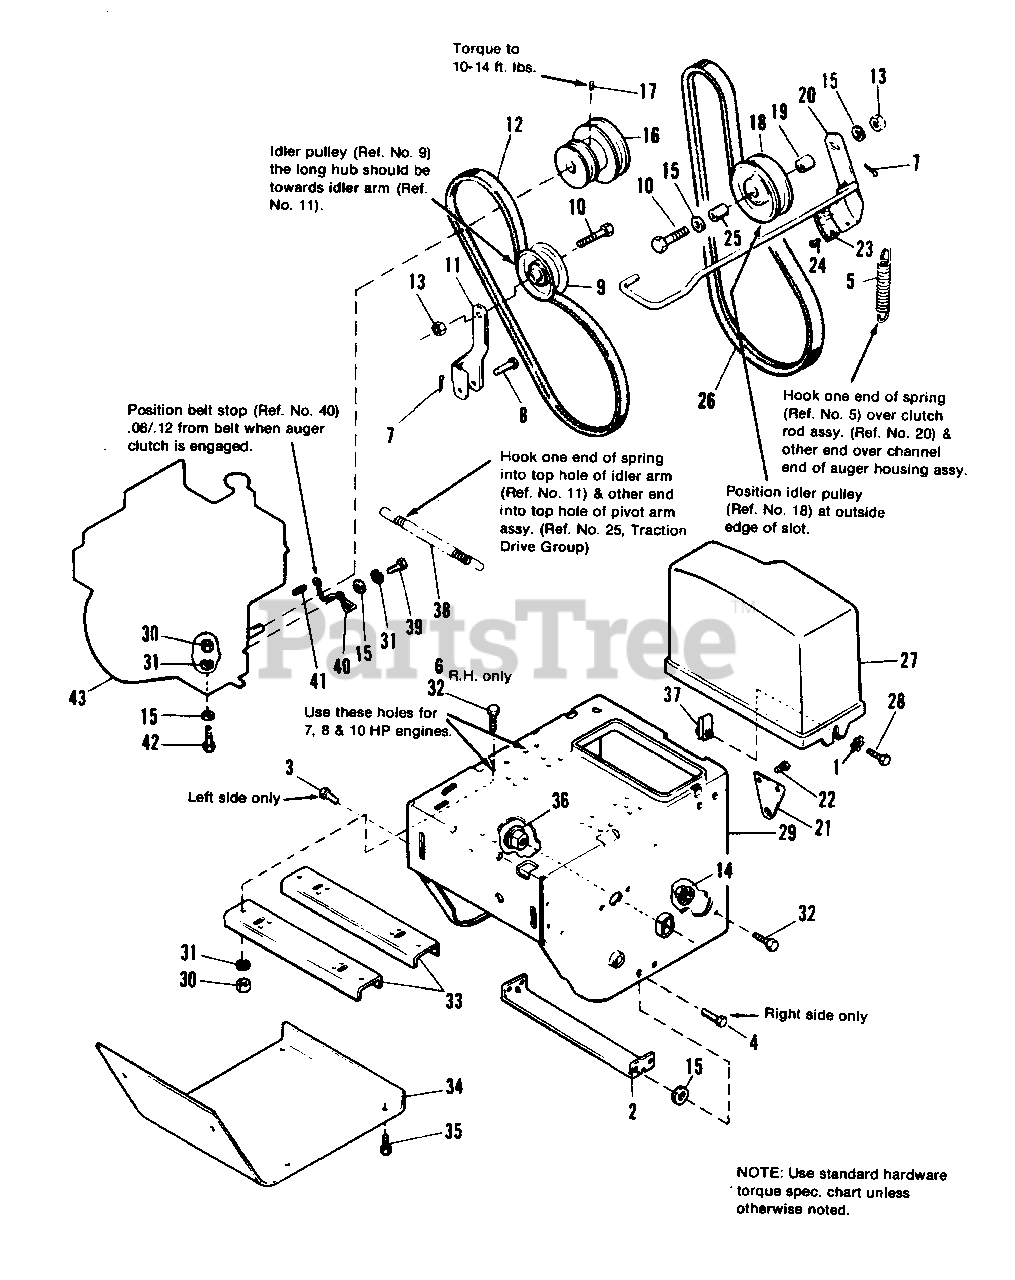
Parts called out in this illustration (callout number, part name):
1	LOCKWASHER, Ext. Tooth, 5/16
2	SUPPORT, Tie Bar
3	SCREW, Taptite, 5/16-18 x 3/8 (left side only)
4	SCREW, TAPTITE, 5/16-18 x 3/4 (ride side only)
5	SPRING, Brake
6	CAPSCREW, Hex Hd., 5/16-18 x 3/4
7	PIN, Cotter, 1/8 x 3/4
8	PIN
9	PULLEY, Idler
10	CAPSCREW, Hex Hd., 3/8-16 x 1-1/2
11	ARM, Idler, Traction
12	BELT, Traction
13	LOCKNUT, Jam, 3/8-16
14	NUT, Hex, Whizlock, 5/16-18
15	WASHER, Flat, 5/16
16	PULLEY, Engine
17	SETSCREW, Socket Hd., 5/16-18 x 5/16
18	PULLEY ASSY.
20	CLUTCH ROD ASSY. (Incl. Ref. Nos. 23 & 24)
21	BRACKET, Clutch Pivot
22	SCREW, Taptite, 1/4-20 x 1/2
26	BELT, Auger Drive
27	GUARD, Belt
28	SCREW, Truss Hd., 5/16-18 x 3/4
29	FRAME, Main
30	NUT, Hex, 5/16-18
31	LOCKWASHER, 5/16
32	CAPSCREW, Whizlock, 5/16-18 x 3/4
33	BRACKET, Engine Mounting
34	COVER, Bottom
35	SCREW, Taptite, 1/4-20 x 3/8
36	BUSHING, Axle
37	NUT, Pal, 5/16-18
38	SPRING, Idler
39	CAPSCREW, Hex Hd., 5/16-24 x 3/4
40	BELT STOP
41	KEY, 1/4 x 1/4 x 1-1/2
42	CAPSCREW, Hex Hd., 5/16-18 x 1-3/4
43	ENGINE, Briggs & Stratton, 8 HP
